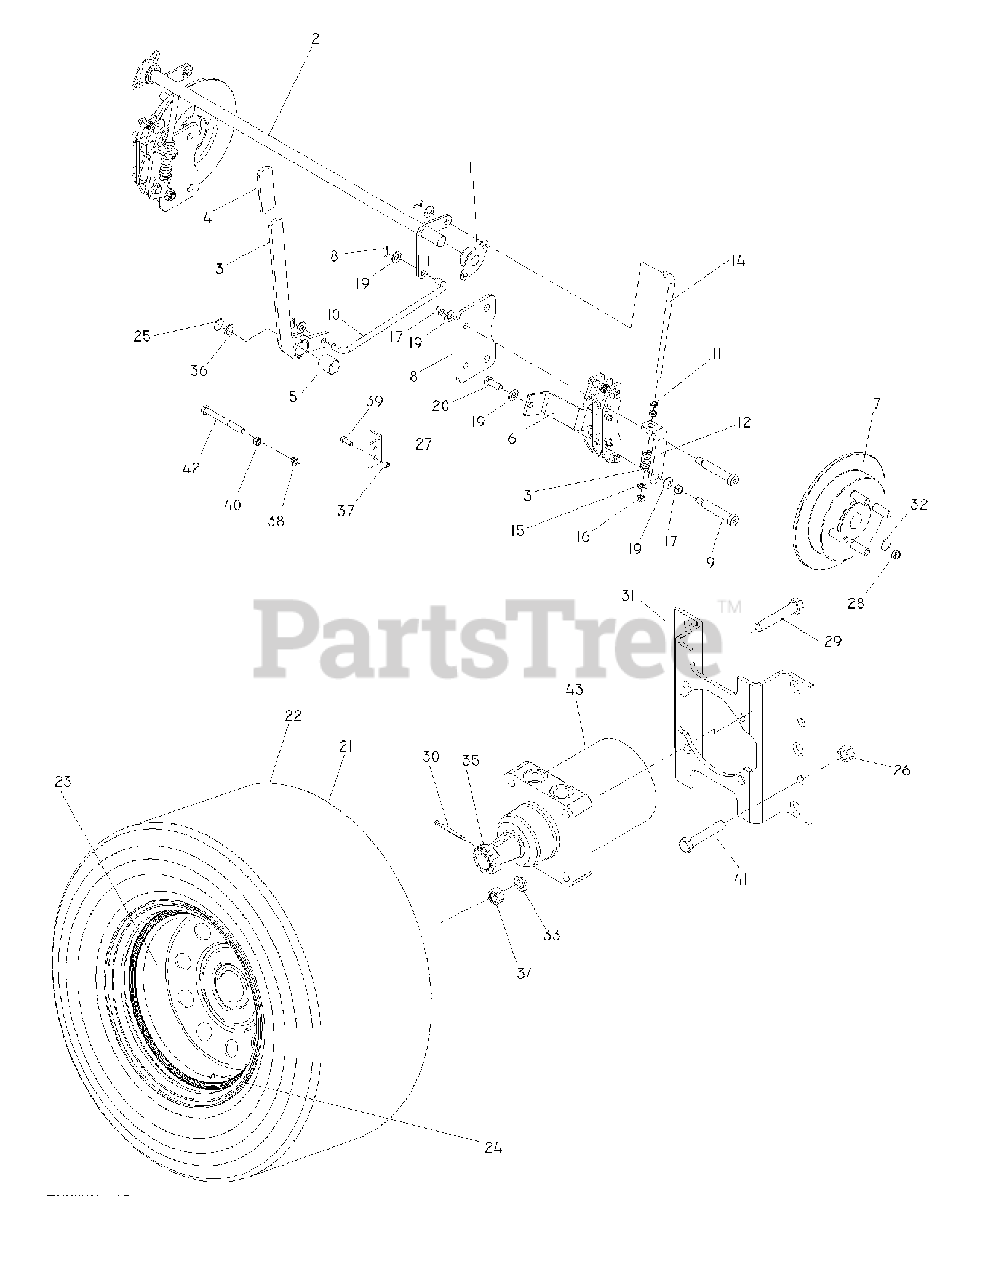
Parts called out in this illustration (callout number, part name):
1	FLANGE BEARING
2	BRAKE CROSS SHAFT
3	LEVER, BRAKE WELDMENT
4	GRIP BRAKE HANDLE
5	BUSHING
6	CALIPER ASSEMBLY
8	PLATE, BRAKE
9	SB 3/8-16 X 2-1-1/2 SKT HDD ZD
10	LINKAGE, BRAKE
11	NUT 3/8-24 JAM
12	BRACKET, L
14	LINKAGE, REAR BRAKE
15	WASHER 3/8 SAE FLAT
16	NUT 3/8F CENTERLOCK
17	NUT HEX 3/8-16 NYLON, THIN
18	COTTER PIN 3/32 X 3/4
19	WASHER 3/8 SAE FLAT
20	HCS 3/8C X 1
21	RP.WHEEL.ASM.23X10.5-12.TURFMA
22	TIRE.TURF.MASTER.23X10.5-12
23	RIM 2.5" NEG OFFSET 8.5" WIDE
24	VALVE STEM TR-412
25	RETAINING RING, 7/8"
26	NUT 1/2-13 HEX NYLOC ZD
27	BRACKET
27	BRACKET, BRAKE SWITCH
28	LUG NUT 1/2F
29	HCS 1/2C X 2 3/4
30	PIN COTTER 4MM X 45MM
31	MOTOR STANDOFF
32	MACHINE BUSHING
33	WASHER 1/2" SPLIT LOCK
34	NUT HEX 1/2
35	NUT 3/4-16 HEX SLTD GR5 ZD
36	BSHG .875 X 1.375 X .074 ZD
37	NUT 1/4-20 NYLOC
38	NUT 3/8-16 NYLOC
39	HCS 1/4C X 3/4 HCS
40	NUT 3/8C WHIZ
41	HCS 1/2C X 1 1/4 SERRATED HEAD
42	HCS 3/8C X 2 1/2
43	WHEEL MOTOR, TJ
